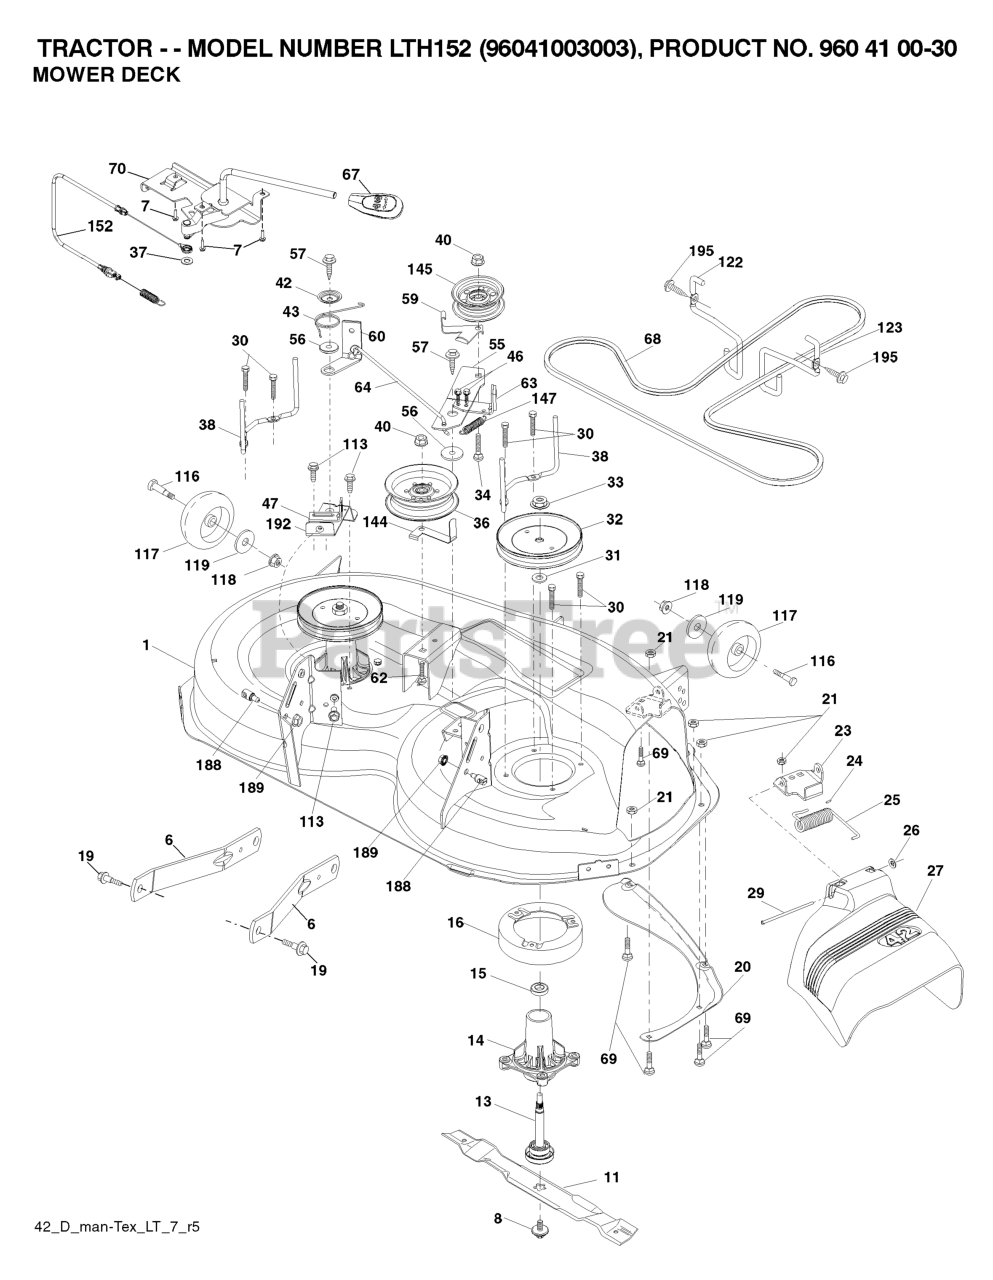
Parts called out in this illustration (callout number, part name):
1	DECK.WELDMENT.42"
6	ARM.SUSPENSION.MOWER.R
7	SCREW
8	BOLT.WASHER.ASM.7/16-2
11	42" HI-LIFT BLADE
13	SHAFT.ASM.MDRL.N/GREASE.38
14	RP.HOUSING.MANDREL.4PT.
16	STRIPPER.MANDREL.ROUND.BLACK
19	BOLT.SHOULDER
20	BAFFLE.VORTEX
21	LOCKNUT
23	BRKT.DEFLECTOR.38"2005+
24	CAP-SLEEVE LT
25	SPRING.TORSION.DEFLECT
26	NUT PUSH M
27	SHIELD.DEFLECTOR.MOWER.42"BLAC
29	ROD.HINGE
30	SCREW, WASHER HEAD
31	WASHER.SPACER.MANDREL
32	PULLEY.MANDREL.5.438.PD
33	NUT.FLANGE.LOCK.TOP
34	BOLT.3/8-16X1.50
36	PULLEY.IDLER.2006
37	WASHER
38	KEEPER.BELT.LH.MANDREL
40	NUT LOCK FLG 3/8-16 UNC
42	SPRING.TORSION.BRAKE
43	SRPING.TORSION.RETAINE
46	SCREW.1/4-20X5/8
47	BRKT.CLUTCH.CABLE
56	SPACER.RETAINER
57	SCREW 3/8-16X1
59	GUARD, BELT
60	ARM BRAKE MOWER
63	ARM BRAKE MOWER
64	LINK BRAKE
67	HANDLE.CLUTCH.CABLE.LT
68	BELT.DRIVE.MOWER.TEX.42"
69	BOLT
70	CLUTCH.ASM.MANUAL.LT.PRED
113	BOLT.5/16HEX.WHS.HD
116	BOLT M
117	WHEEL.GAGE.HALF.SPOKED
118	LOCKNUT
119	WASHER.5/16.FLAT.STE.STD.
122	KEEPER BELT ENGINE LH
123	KEEPER BELT RH
144	KEEPER.BELT.MOWER
145	PULLEY.IDLER.48"PRIMARY
147	RETURN SPRING
152	CLUTCH CABLE
188	STUD.FASTNER.W/ANTI-ROTATE
189	NUT LOCK HEX FLANGE 5/16-18
192	BRKT.BRAKE.STAND.LH.
195	SCREW, 3/8-16X3/4
